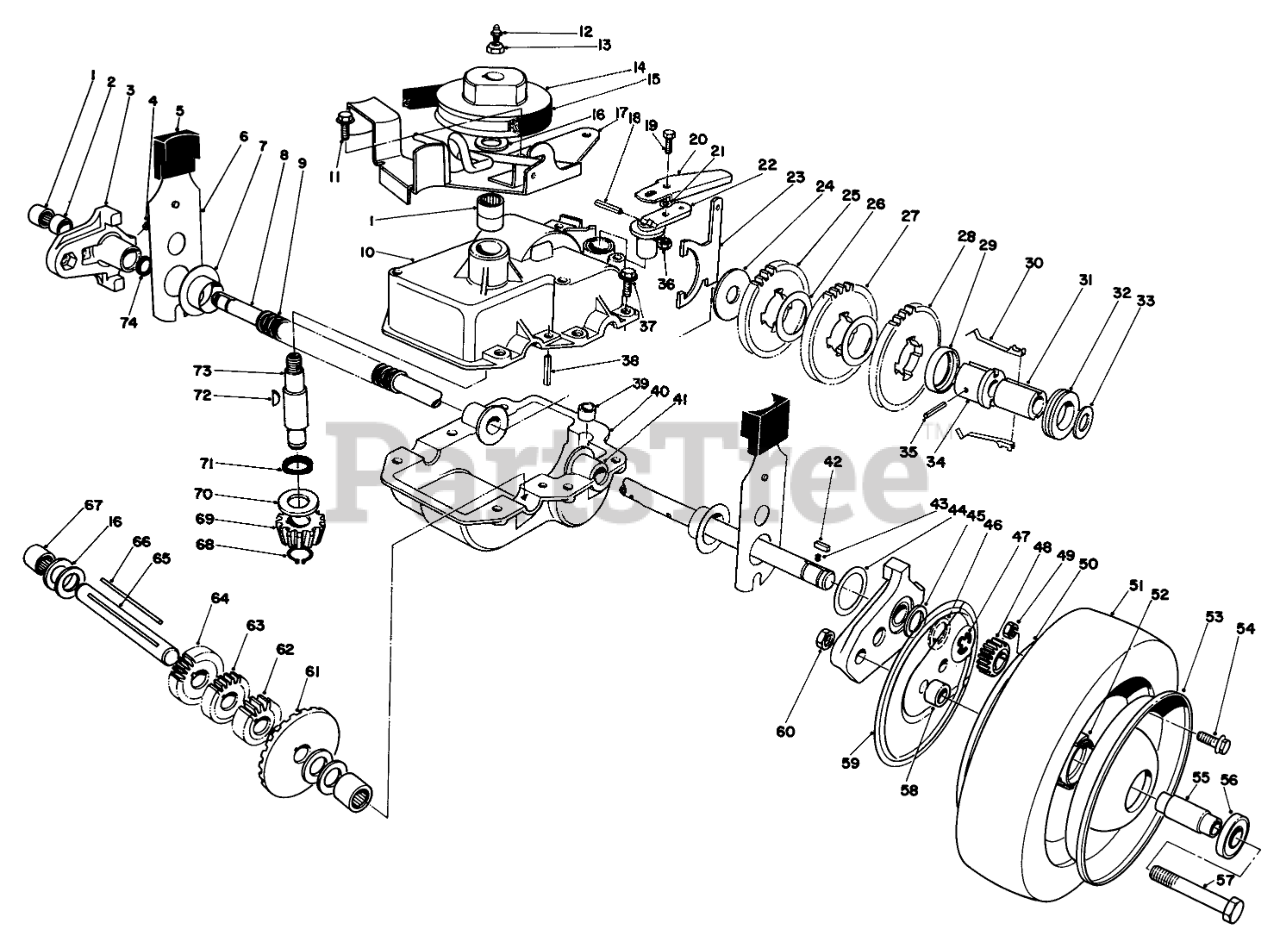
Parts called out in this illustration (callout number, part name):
1	BEARING-NEEDLE
2	BUSHING
3	Pivot Arm Assembly (Incl. Ref. #1-2, 4 & 69)
4	FITTING-GREASE
5	KNOB-ARM
6	Spring Arm
7	CAP-END
8	Output Shaft
9	CONDUIT-CONVOLUTED, SPLIT
10	Case Upper
11	SCREW
12	FITTING-GREASE
13	NUT-HEX
14	PULLEY
15	V-BELT
16	WASHER-THRUST
17	BELT GUIDE BRKT W A
18	PIN-COIL
20	Cover-Shift Lever
21	WASHER-FLAT
22	LEVER-SHIFT
23	Shift Yoke
24	WASHER
25	GEAR-38T
26	WASHER
27	GEAR-42T
29	KEY RETAINER
30	KEY-SHIFT
31	SLEEVE
32	COLLAR-SHIFT
33	WASHER-PLAIN
34	Body-Sleeve
35	PIN-SPIROL
36	NUT-LOCK, NI
37	SCREW-HWHTF
38	ROLL PIN 3/16 X 1 IN
39	BUSHING-YOKE
40	Case-Lower
41	BUSHING
42	KEY RECTANGULAR
43	Spring
44	WASHER
45	THRUST WASHER
46	KEYED WASHER
47	RING-RETAINING
48	GEAR-PINION
49	NUT-LOCK, NI
50	Wheel-Inner Half
52	HUB-BEARING
53	Wheel-Half
54	SCREW-HHF
55	SPACER-BEARING
56	BEARING-WHEEL
57	SCREW-HH
58	SPACER-WHEEL
59	WHEEL COVER
60	NUT-LOCK, NI
61	BEVEL GEAR
62	GEAR-12T
63	GEAR-14T
64	GEAR-18T
65	Shaft-Intermediate
66	Key Square
67	BEARING-NEEDLE, CLOSED
68	RING-RETAINING
69	PINION-BEVEL
70	WASHER-THRUST
72	KEY-WOODRUFF
73	Shaft Input
